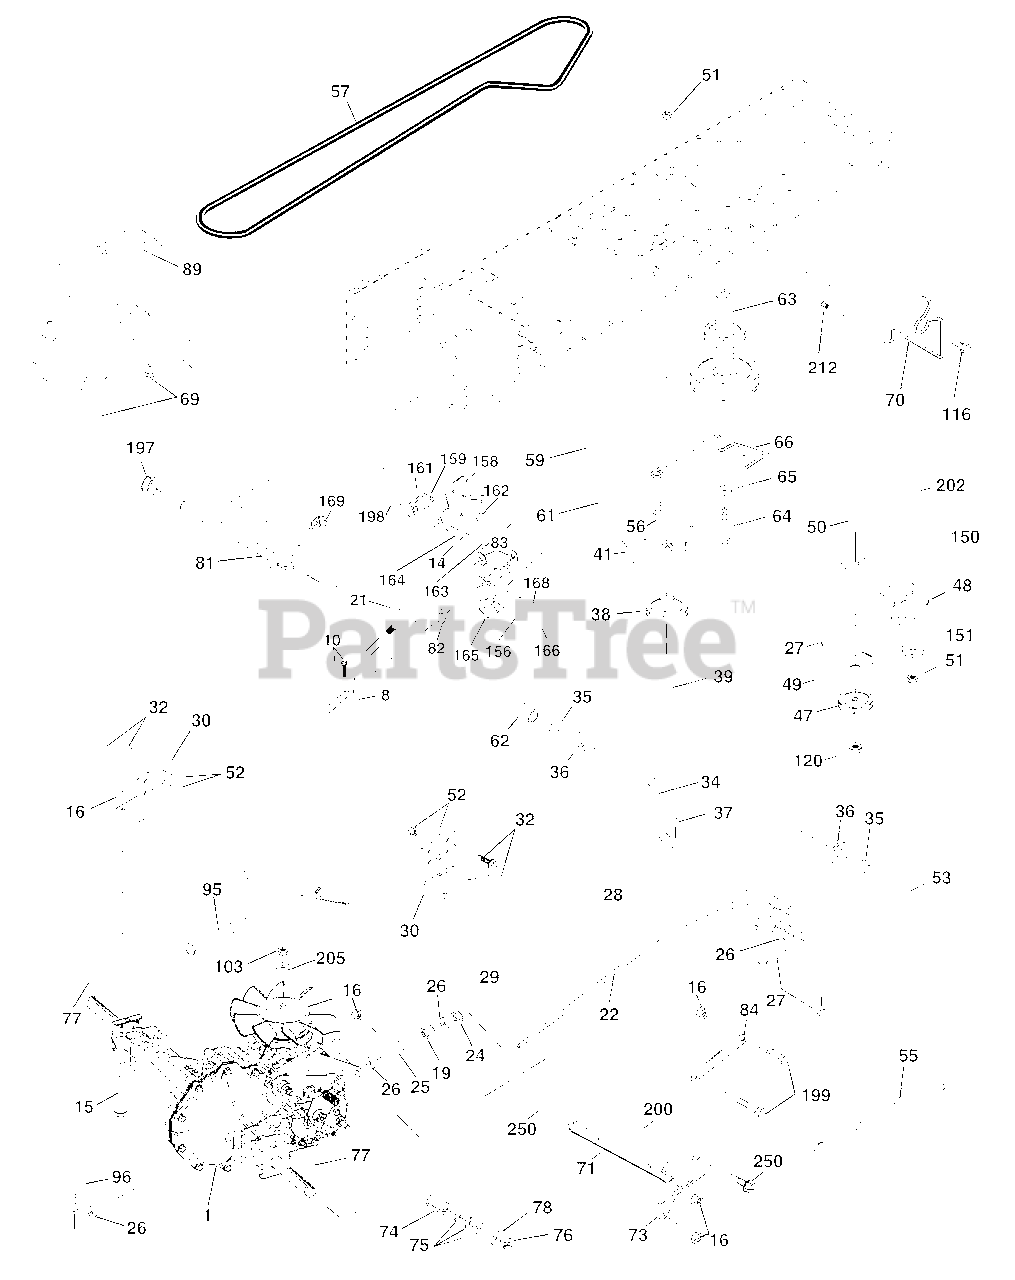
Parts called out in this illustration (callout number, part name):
8	Rod Shift Fender
10	Pin Cotter 1/8 x 1 CAD
14	Washer Lock Hvy Helical 1/4
15	Bolt Hex Flg Hd 5/16-18 X Gr.5
16	Nut Lock Hex W/Ins. 5/16-18 Unc P
19	Nut Lock Hex W/Wsh 3/8-16 Unc
21	Knob, Deluxe
22	Rod, Brake Hydro
24	Nut
25	Spring, Brake Rod
26	Washer
27	Pin Cotter 1/8 x 3/4 CAD.
28	Rod, Parking Brake
29	Cap, Parking Brake
30	Bracket, Transaxle
32	Bolt Hex Hd 5/16-18 Unc x 3/4
34	Shaft, Foot Pedal
35	Bearing, Nylon
37	Pin, Roll
38	Pulley, Composite
39	Bolt
41	Keeper, Belt Idler
47	Pulley, Idler, V-Groove
48	Bellcrank Clutch Grnd Drv Stl
49	Retainer, Belt
50	Bolt
52	Nut Crownlock 5/16-18
53	Link, Clutch
55	Spring, Return, Clutch
56	Screw 3/8-16 x 1-1/4
57	V-Belt, Ground Drive
59	Keeper, Center Span
61	Screw 3/8-16 x .875
62	Cover, Pedal
63	Pulley, Clutch Eng
64	Bolt Hex 7/16-20 x 4 Ga. 5
65	Washer
66	Keeper Belt Engine
69	Screw Hex Wsh Hi-Lo 1/4-1/2 Unc
70	Guide Belt Mower Drive RH
71	Strap Torque Lh Hydro
73	Strap Torque Rh Hydro
74	Spacer, Axle
75	Washer 25/32 x 1-1/4 x 16 Gauge
77	Key, Square
78	Washer 25/32 x 1-5/8 x 16 Gauge
81	Shaft Asm. Cross Hydro
82	Spring Torsion T/A
83	Washer 17/32 x 3/4 x 16 Ga.
84	Link Transaxle
89	Console, Shift
95	Control Asm Bypass Hydro
96	Retainer Spring 1" Zinc/Cad
103	Nut Hex Jam Toplock 1/2-20 Unf
116	Boulon 3/8-16 x 1
120	Nut Lock Flg 3/8-16
150	Spacer Retainer
151	Washer 13/32 x 2 x 10 Ga.
156	Washer Srrtd 5/16 ID x 1.0 x .125 Tk
158	Bracket Shift Mount
159	Hub Tapered Flange Shift LT
161	Bolt Rdhd Sqnk 1/4-20 x 3/4 Gr. 5
162	Nut Crownlock 1/4-20 Unc
163	Bolt Hex Fin 1/4-20 unc x 1 Gr. 5
164	Washer 5/8 x .281 x 10 Ga
165	Bracket Pivot Lever
166	Screw 5/16-18 x 5/8 TT Yellow
168	Bolt Shoulder 5/16-18 x .561 TT
169	Plate Fastening Cross Shf. STLT/CRD
197	Nyliner Snap-In 5/8" ID
198	Washer Nyl. 7/8 ID x .105"
199	Bolt Shoulder 5/16-18 Unc
200	Bolt Rdhd Sq Neck 5/16-18unc x 1
202	Bolt Carr Sh 3/8-16 x 1-3/4 Gr. 5
205	Washer 17/32 x 1 x 16 Ga.
212	Nut Hex Flg Lock
250	Screw 3/8-16 x 3/4
